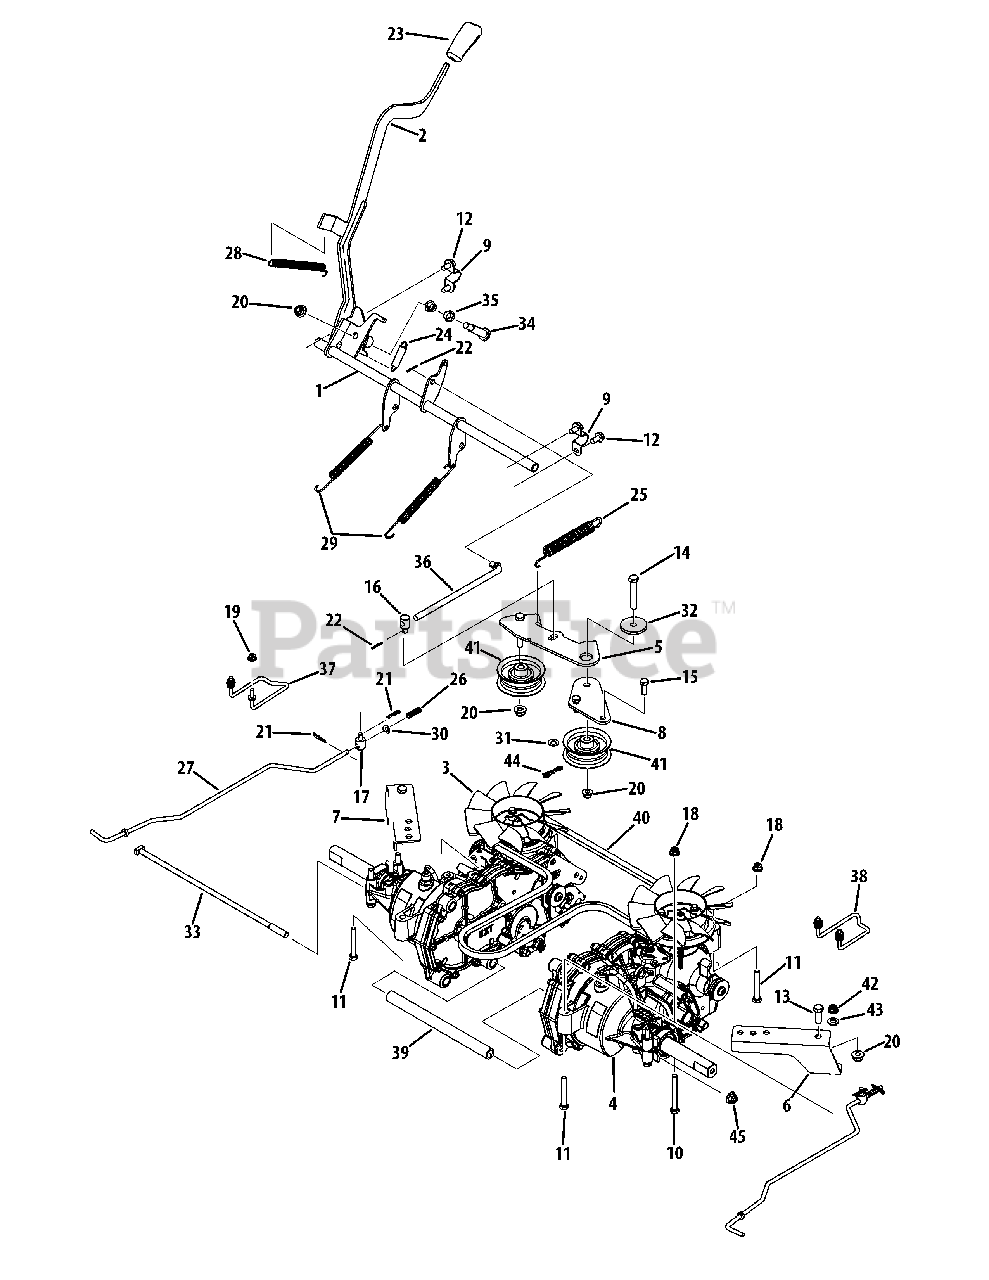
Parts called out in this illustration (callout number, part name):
1	Brake Shaft Assembly
2	Brake Handle Assembly
3	LH Transmission Assembly
4	RH Transmission Assembly
5	Idler Bracket
6	RH Mount Bracket
7	LH Mount Bracket
8	Idler Mount Plate
9	Shaft Mount Bracket
10	Hex Screw, 5/16-18 x 2.75
11	Hex Screw, 5/16-18 x 2.25
12	Hex Washer Screw, 5/16-18 x .750
13	Hex Screw, 3/8-16 x 1.00
14	Hex Screw, 3/8-16 x 2.25
15	Hex Screw, 5/16-18 x .875
16	Ferrule, 3/8-24 x .375
17	Ferrule, .325 x .312
18	Flange Lock Nut, 5/16-18
19	Flange Lock Nut, 1/4-20
20	Flange Lock Nut, 3/8-16
21	Cotter Pin, .072 x 1.13
22	Cotter Pin, 3/32 x .750
23	Selector Handle
24	Extension Spring, .48 x 2.03
25	Extension Spring, .75 x 6.02
26	Compression Spring, .34 x 1.0
27	Transmission Bypass Lever Wire
28	Extension Spring, .50 x 6.37
29	Extension Spring, .500 x 7.0
30	Spring Washer, .265 x .562 x .025
31	Thrust Washer, .375 x .70 x .030
32	Shoulder Spacer, .884 x .190
33	Rod, .405 x 14.00
34	Shoulder Screw, .498 x 1.635
35	Flange Bearing, .500 x .34
36	Disengage Brake Rod
37	LH Keeper Rod
38	RH Keeper Rod
39	Transmission Spacer, 9.40
41	Flat Idler Pulley, 2.75
42	Hex Lock Nut, 5/16-24
43	Flat Washer, .330 x .630 x .064
44	Bow-Tie Cotter Pin
45	Flange Lock Nut, 7/16-20
